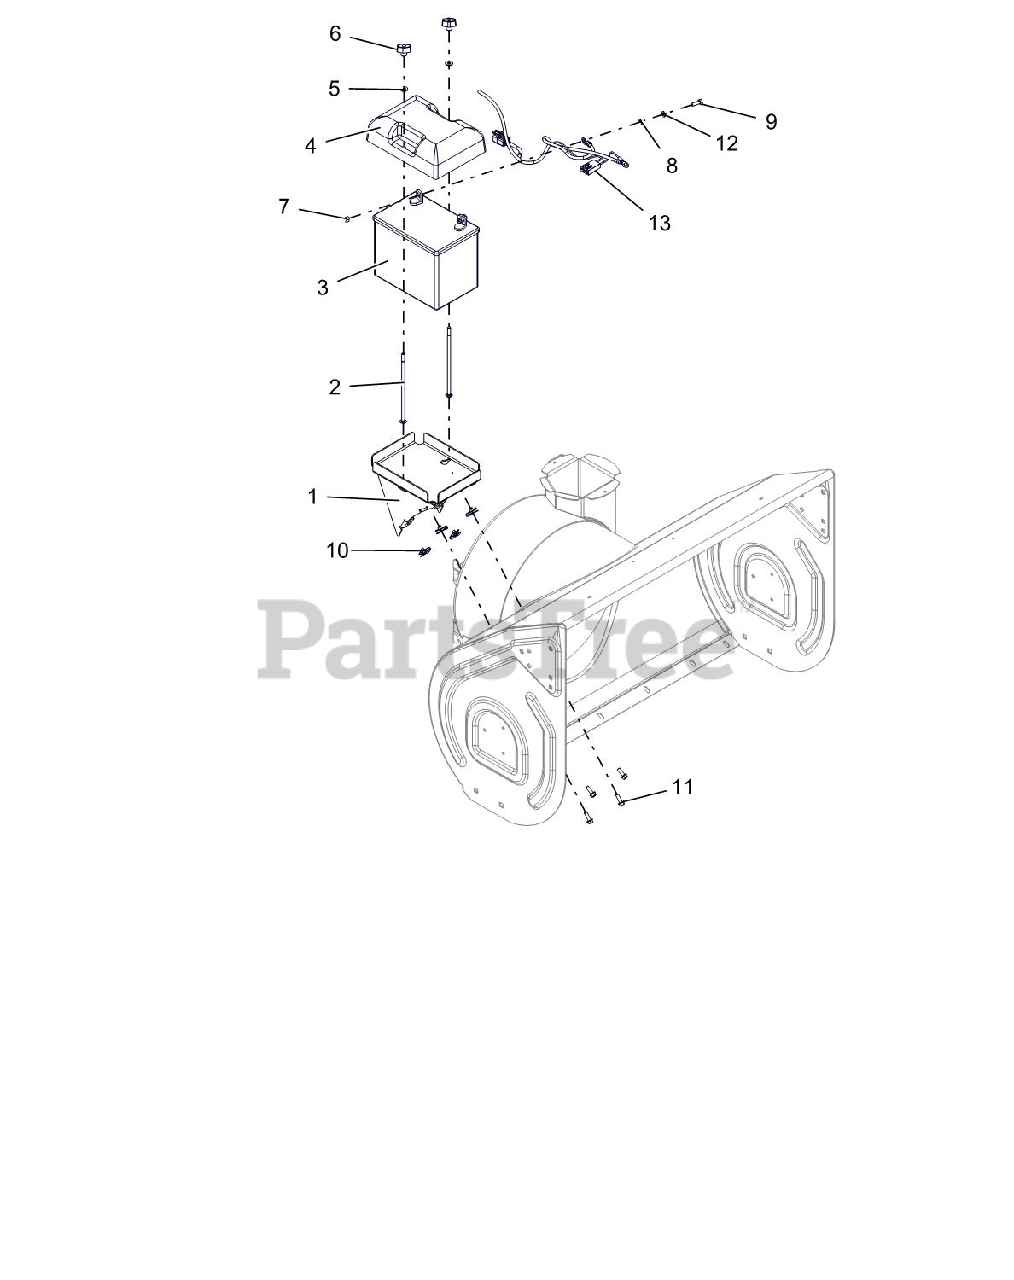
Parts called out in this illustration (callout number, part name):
1	ASSY, BATTERY TRAY WITH CLIPS
2	@BLT-RDHDSQNK .25-20X7.00 G2YZ
3	BATTERY, 300 CCA 10U1L
4	COVER, BATTERY
5	@WSHR-FL-STL.281X.62X.065 YWZC
6	KNOB, WING - .25-20 UNC
7	@NUT-HEX .25-20 YWZC
8	@WSHR-LK .25X.062 REG YWZC
9	@BLT-HEX .25-20X.75 GR5 YWZC
10	NUT-RTNR .25-20X.56
11	BLT-HEX .25-20X.75 HWH YZ GR5
12	WSHR-FL-STL .265X.50X.087YWZC
13	HARNESS, ELEC - 12V BRIGGS
